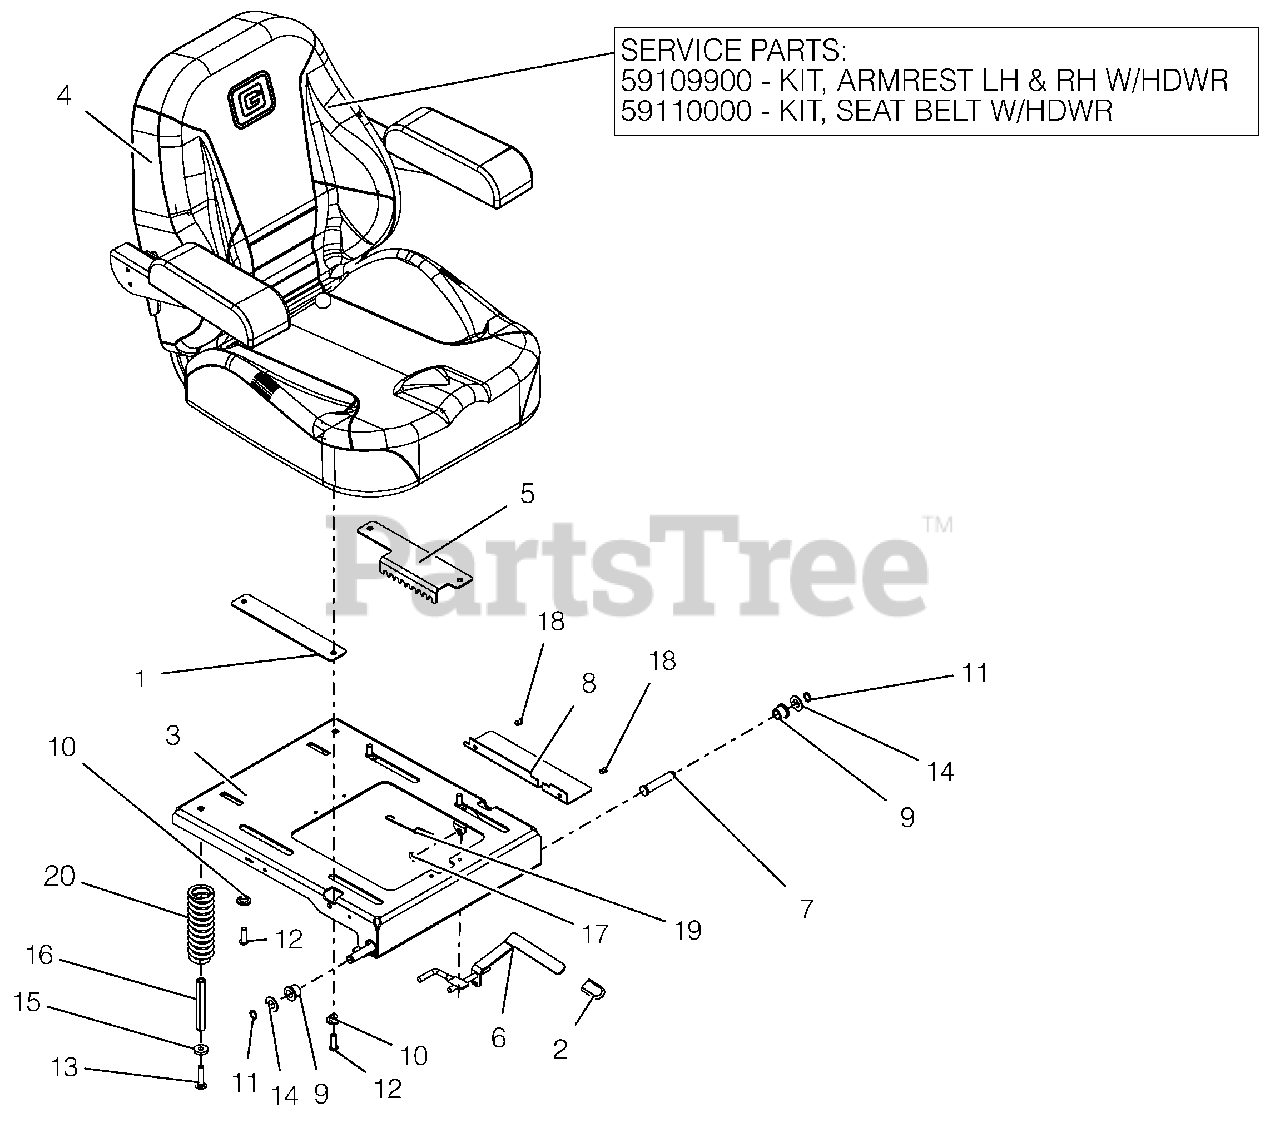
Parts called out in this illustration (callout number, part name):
1	PLATE, ADJUSTABLE SEAT SLIDE
2	GRIP, SEAT LEVER, GREY
3	WLDMT, SEAT PLATE HD
4	KIT, LH&RH ARM REST-05007300
4	KIT-SEAT BELT REPLACE-05007300
5	PLATE, HD SEAT ADJUSTMENT
6	WLDMT, SEAT SLIDE LEVER
7	PIN, SEAT PIVOT -.500X2.31
8	GUARD, SEAT PLATE
9	BSHG, FLG .516X.750X.625X.937
10	BSHG-FLG .32X.500X.344X.880
11	RG-RTNG-EXT .500X.050 (SNAP)
12	SCR-SKH .31-18X1.0 BTNHD YWZC
13	@BLT-RDHDSQNK .31-18X1.50 G5YZ
14	WSHR-FL-STL.531X1.00X.063 YWZC
15	WSHR-FL-STL .328X.87X.179 YWZC
16	NUT, COUPLING 5/16X18 X 3.75
17	NUT-PUSH .312
18	RIVET, .1875 AL/AL .126-.250
19	SG-TENS .06X.482X5.35
20	SPRING, COMPRESSION SEAT 224LB
